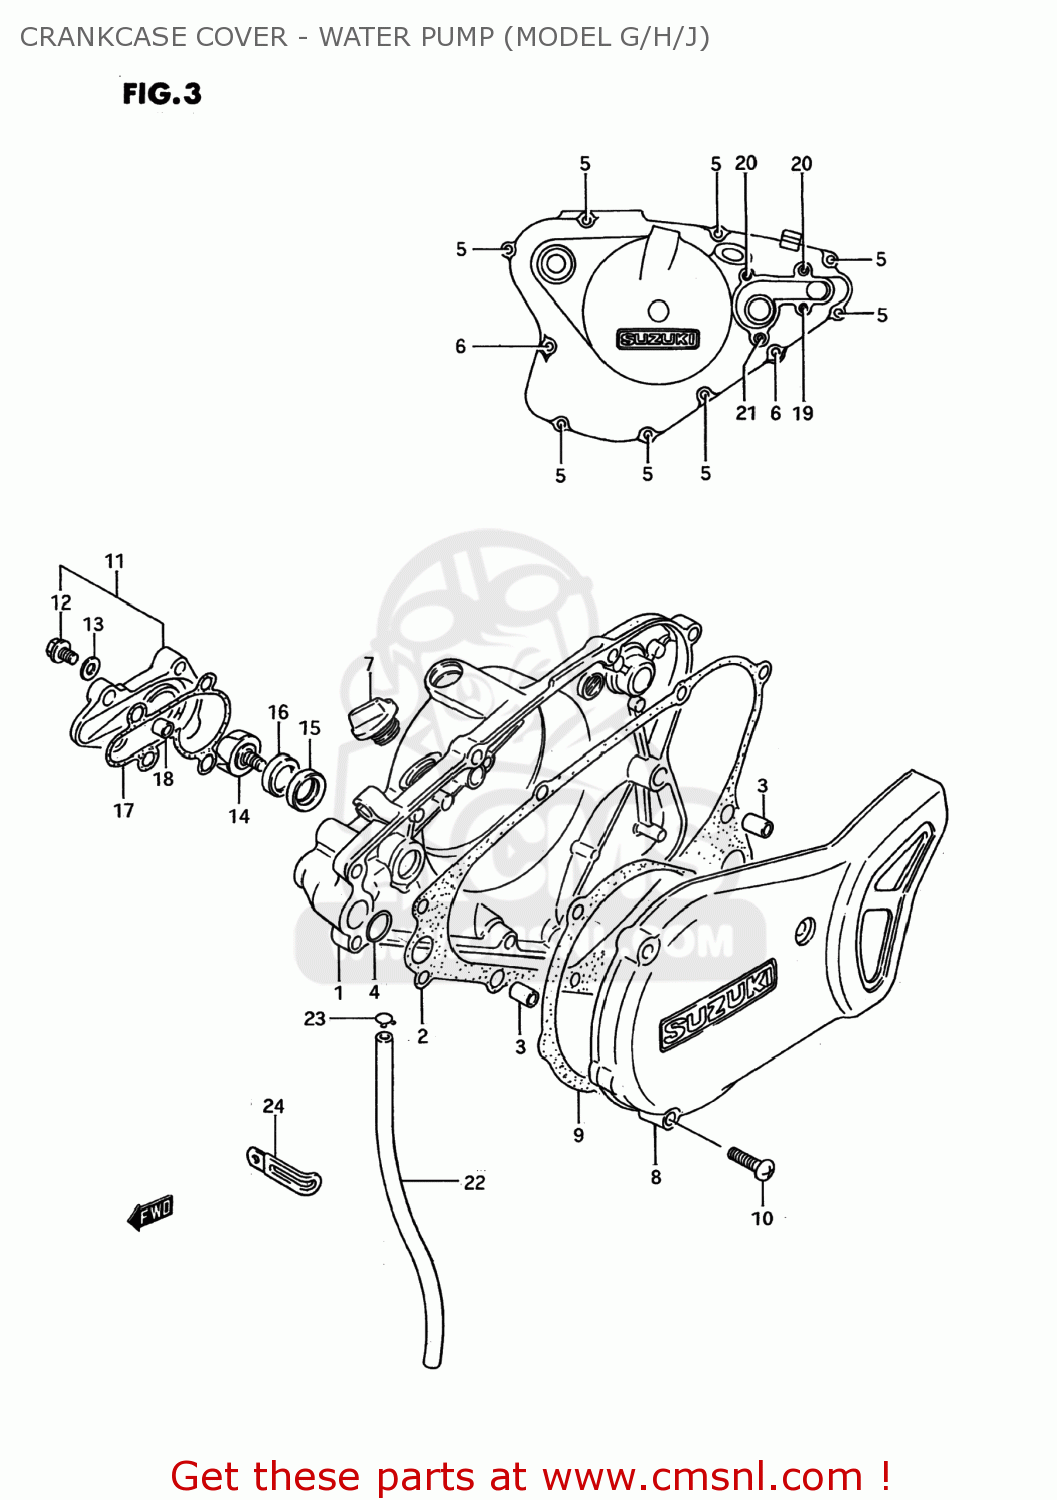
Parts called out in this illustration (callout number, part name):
1	COVER SET,CLUTCH
2	GASKET,CLUTCH COVER (NAS)
3	PIN
4	O RING(D:1.9,ID:14.5)
5	SCREW
6	SCREW
7	PLUG SET
8	COVER,MAGNETO
9	GASKET,MAGNETO COVER (NAS)
10	SCREW
11	CASE,WATER PUMP
12	BOLT,BLEEDER
13	GASKET (NAS)
14	IMPELLER,WATER PUMP
15	SEAL,OIL(12X24X7)
16	SEAL,OIL(12X24X6.4)
17	GASKET,WATER PUMP CASE (NAS)
18	PIN
19	SCREW
20	SCREW
21	SCREW 6X30
22	HOSE(4X7X600)
23	CLIP
24	CLAMP
